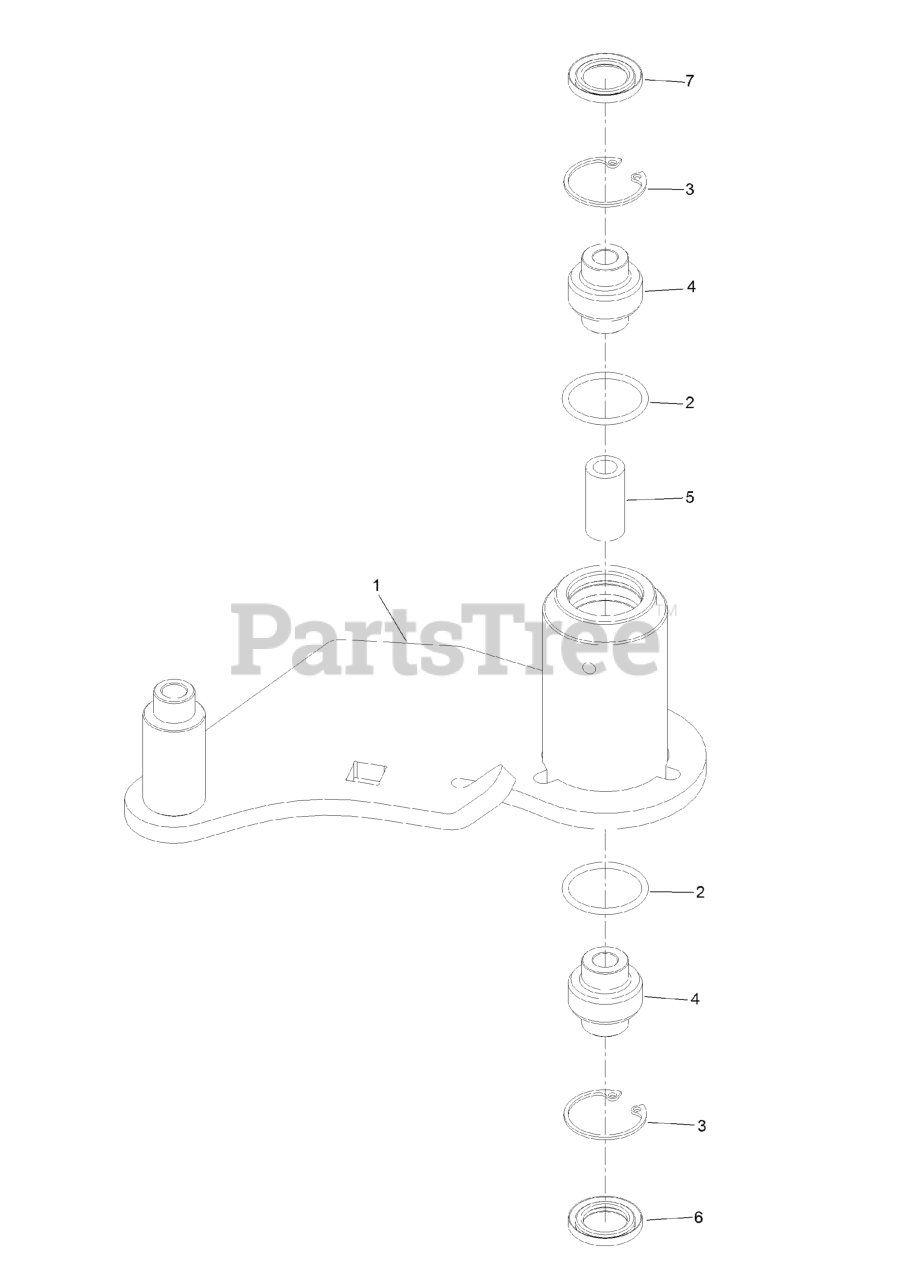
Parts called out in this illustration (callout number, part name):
1	Idler-Deck
3	RING-SNAP
4	BEARING-SPHERICAL
6	SEAL-LIP, DOUBLE
7	SEAL-LIP, SINGLE
